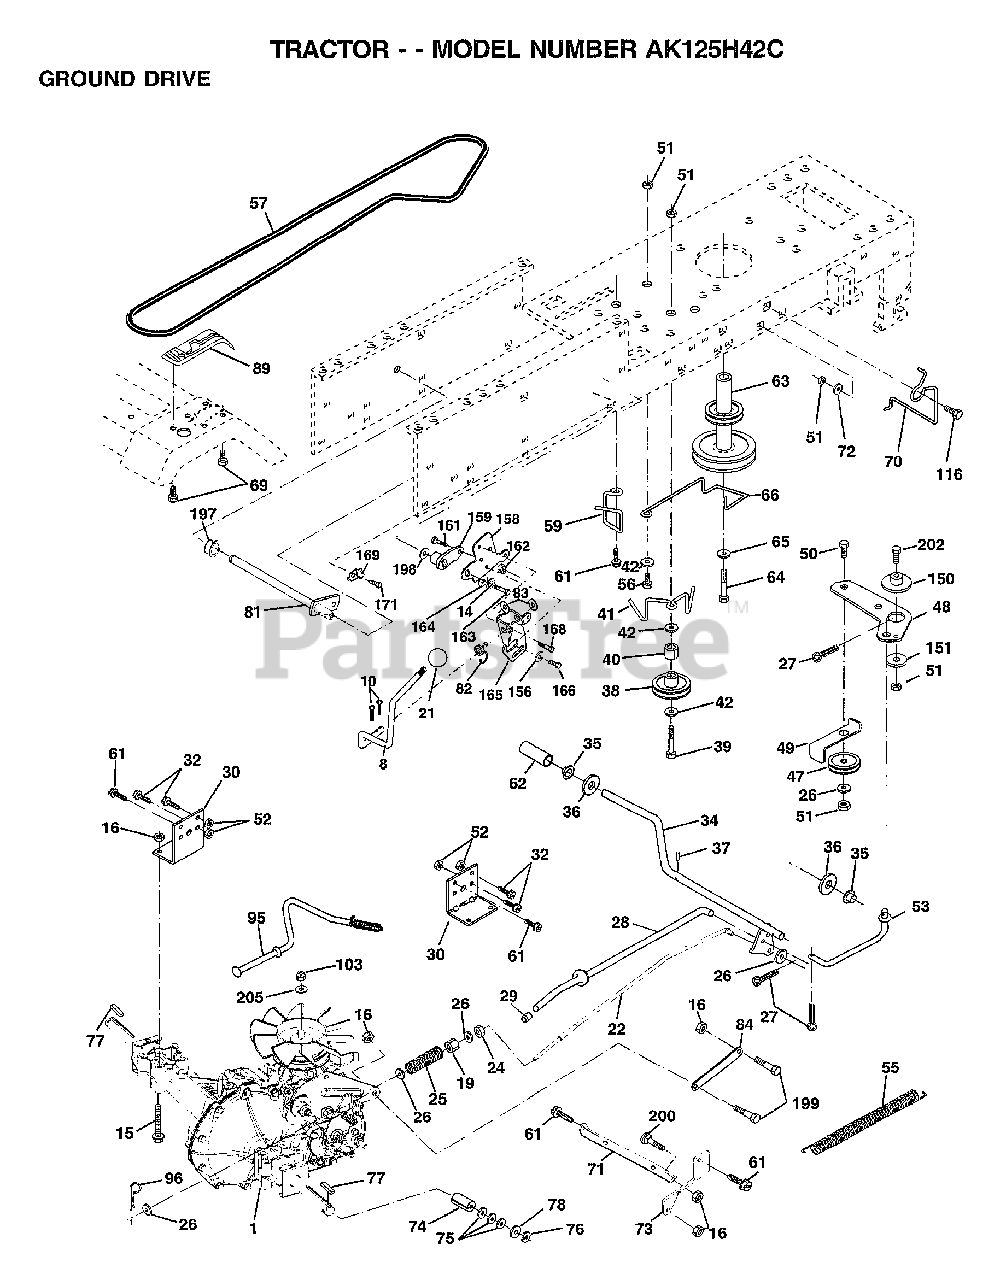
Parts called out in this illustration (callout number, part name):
8	ROD.SHIFT.FENDER.ADJ.LT.CRD
10	PIN COTTER 1/8
14	LOCKWASHER
15	BOLT.HX.FLG.5/16
16	NUT
19	NUT
21	KNOB T (1/2-HOLE)
22	ROD BRAKE HYDRO
24	NUT
25	SPRING ROD LT
26	WASHER
27	COTTER PIN
28	ROD.BRAKE.PARK.LT
29	PLUNGER CAP T
30	TRANSAXLE MTG BKT
32	BOLT
34	SHAFT ASM-PEDAL F
35	NYLON BEARING
36	WASHER LT
38	FLAT IDLER PULLEY
39	BOLT
40	SPACER T
41	"KEEPER,BELT.IDLER FLAT"
42	WASHER
48	BELLCRANK.CLUTCH
49	RETAIN BELT
53	"LINK, CLUTCH T"
55	"SPRING, RETURN LT"
57	"BELT.GD DRV 82"""
59	KEEPER BELT SPAN CTR
61	SCREW
62	PEDAL COVER T
63	PULLEY.ENGINE
64	BOLT
65	LOCKWASHER
66	KEEPER-BELT
69	SCREW HEXWSH H-L
70	KEEPER BELT ENG
71	STRAP TORQUE LH HYDRO
72	WASHER
73	STRAP TORQUE RH HYDRO
74	SPACER
75	WASHER
76	E-RING LT
77	SQUARE KEY
78	WASHER
81	SHAFT
82	"SPRING,TORSION"
83	WASHER
84	LINK TRANSAXLE
89	CONSOLE HYDRO
95	CONTROL ASSY
96	RETAINER M
116	BOLT RDHD 3/8-16
150	BUSHING.BELLCRANK.GRD.DR
151	WASHER
156	WASHER.SRRTD.5/16
158	BRKT.SHIFT.MOUNT
159	HUB.SHIFT
161	BOLT T
164	WASHER.5/8X.281X10GA
165	BRKT.PIVOT.LEVER
166	SCREW.5/16-18X5/8
168	BOLT.SHOULDER.5/16-18X.561
169	PLATE.FASTENING
171	SCREW LT
197	NYLINER SNAP-IN
198	WASHER NYLINER
199	BOLT SHOULDER
200	BOLT
202	BOLT.3/8-16X1.50
